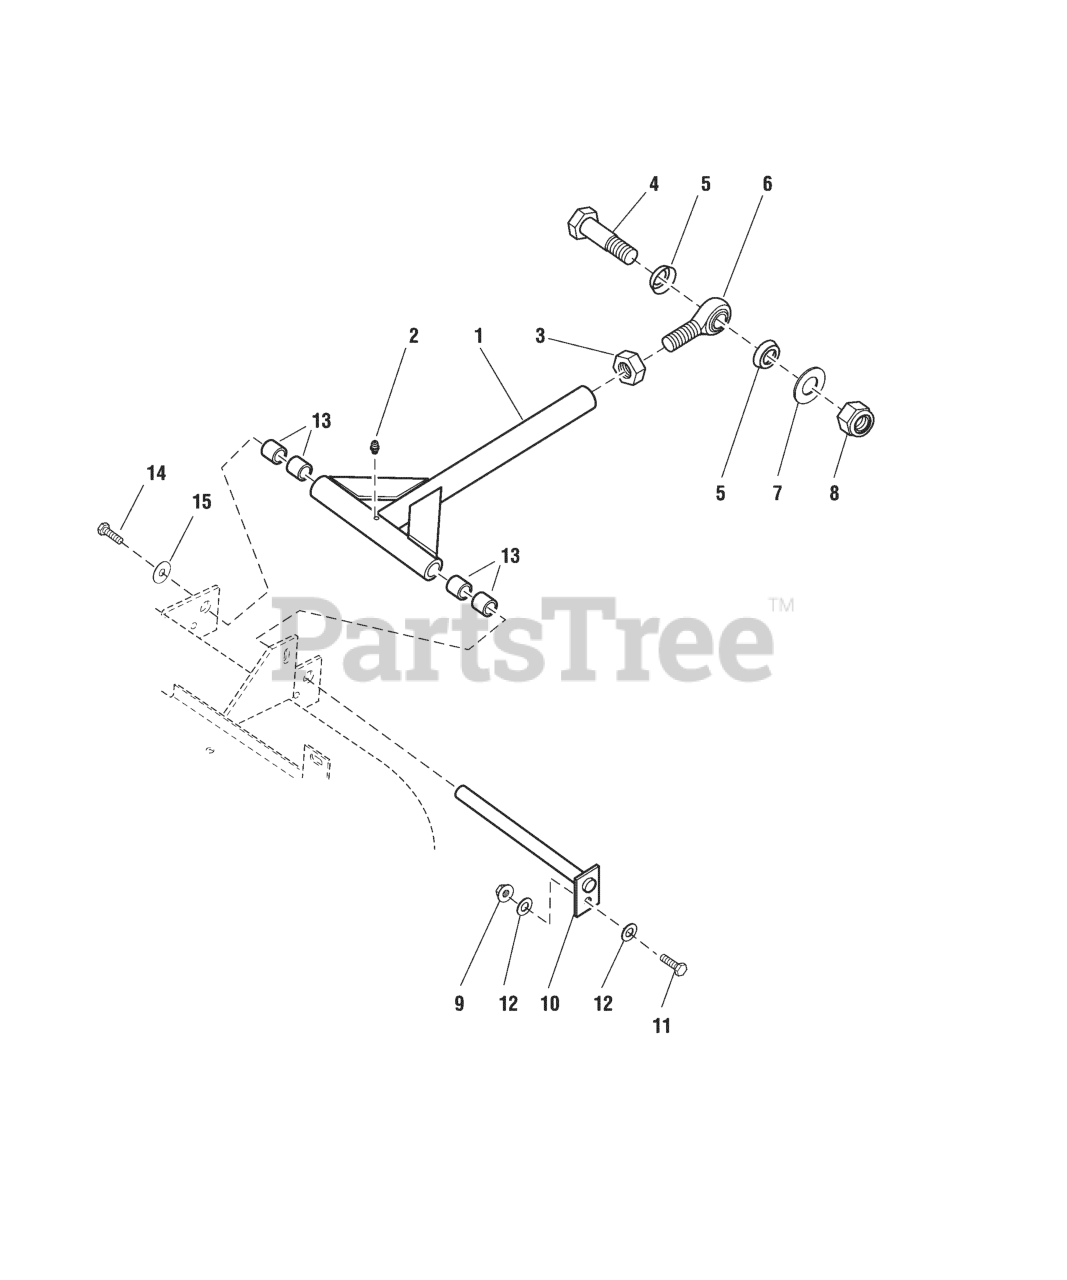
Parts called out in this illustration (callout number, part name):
1	ASSM, DECK PUSHER BAR
2	GREASE FITTING
3	NUT, 3/4-16 Hex Jam
4	BOLT, 3/4-16 x 3
5	ROD END SEAL
6	BALL JOINT, 3/4-16 Male
7	WASHER, 3/4 SAE
8	NUT, 3/4-16 Hex Nylon Lock
9	NUT, 3/8-16 HEX NYLON LOCK
11	BOLT, 3/8-16 X 1-1/4" GD5 CZ
12	WASHER, 3/8 SAE
13	BUSHING, .75 X 1.00 X 1.00, PLASTIC
14	BOLT, 3/8-16 X 1" GD5 CZ
15	WASHER, .390 X 1.50 X .109 YZ
